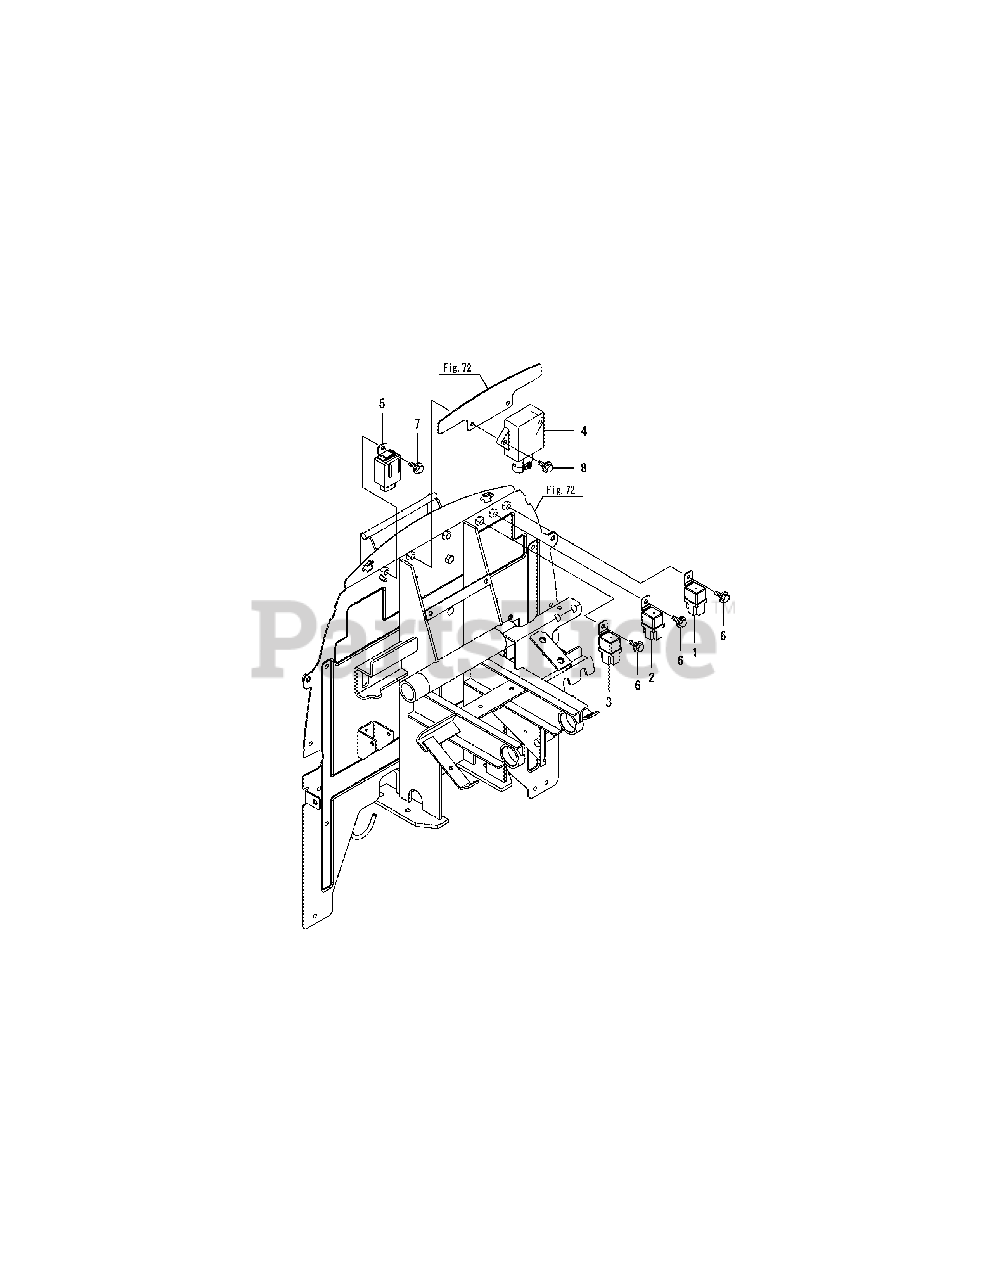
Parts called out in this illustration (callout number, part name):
6	BOLT M 6X 12 PLATED
7	BOLT M 6X 12 PLATED
8	BOLT M 6X 20 PLATED
